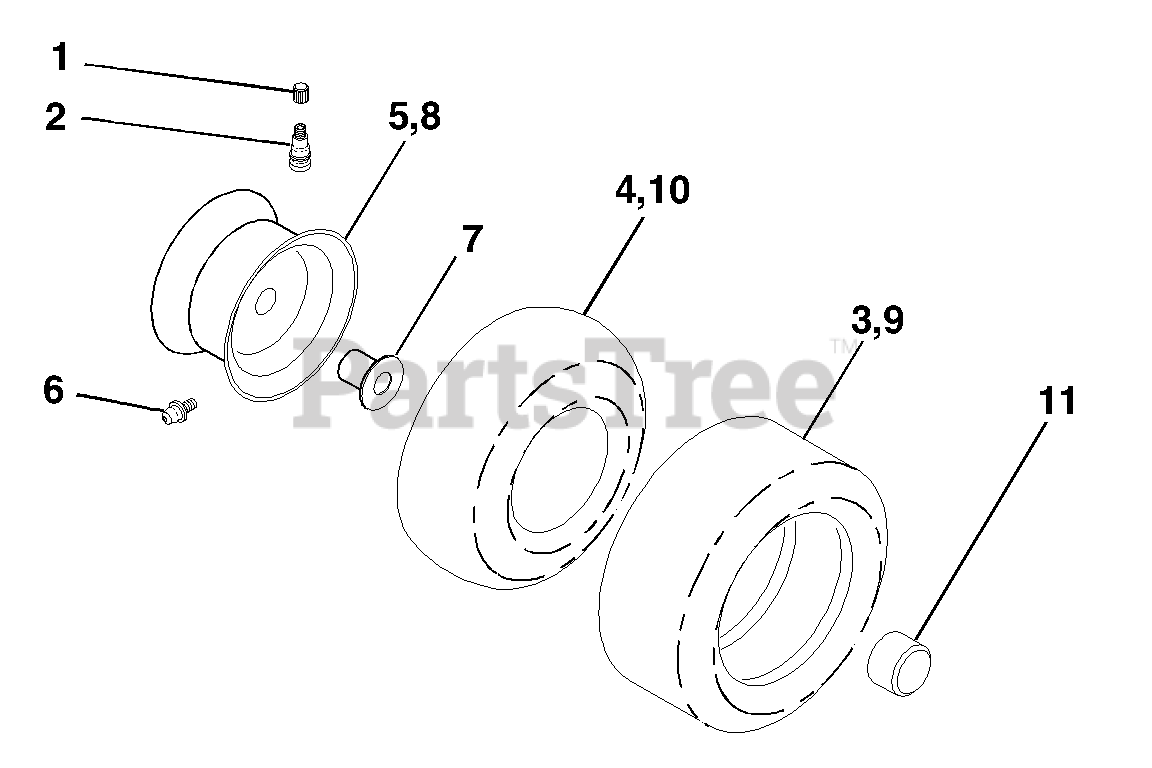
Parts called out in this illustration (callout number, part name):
1	Cap Valve Tire
2	Stem Valve
3	Tire F T 15 X 6 0 - 6 Service
4	Tube Front (Service Item Only)
5	Rim Asm 6" front Service
6	Fitting Grease (Front Wheel Only)
7	Bearing Flange (Front Wheel Only)
8	Rim Asm 8" rear Service
9	Tire R T 20x10-8 Service
10	Tube Rear (Service Item Only)
11	Cap Axle Blk 1 50 X 1 00
